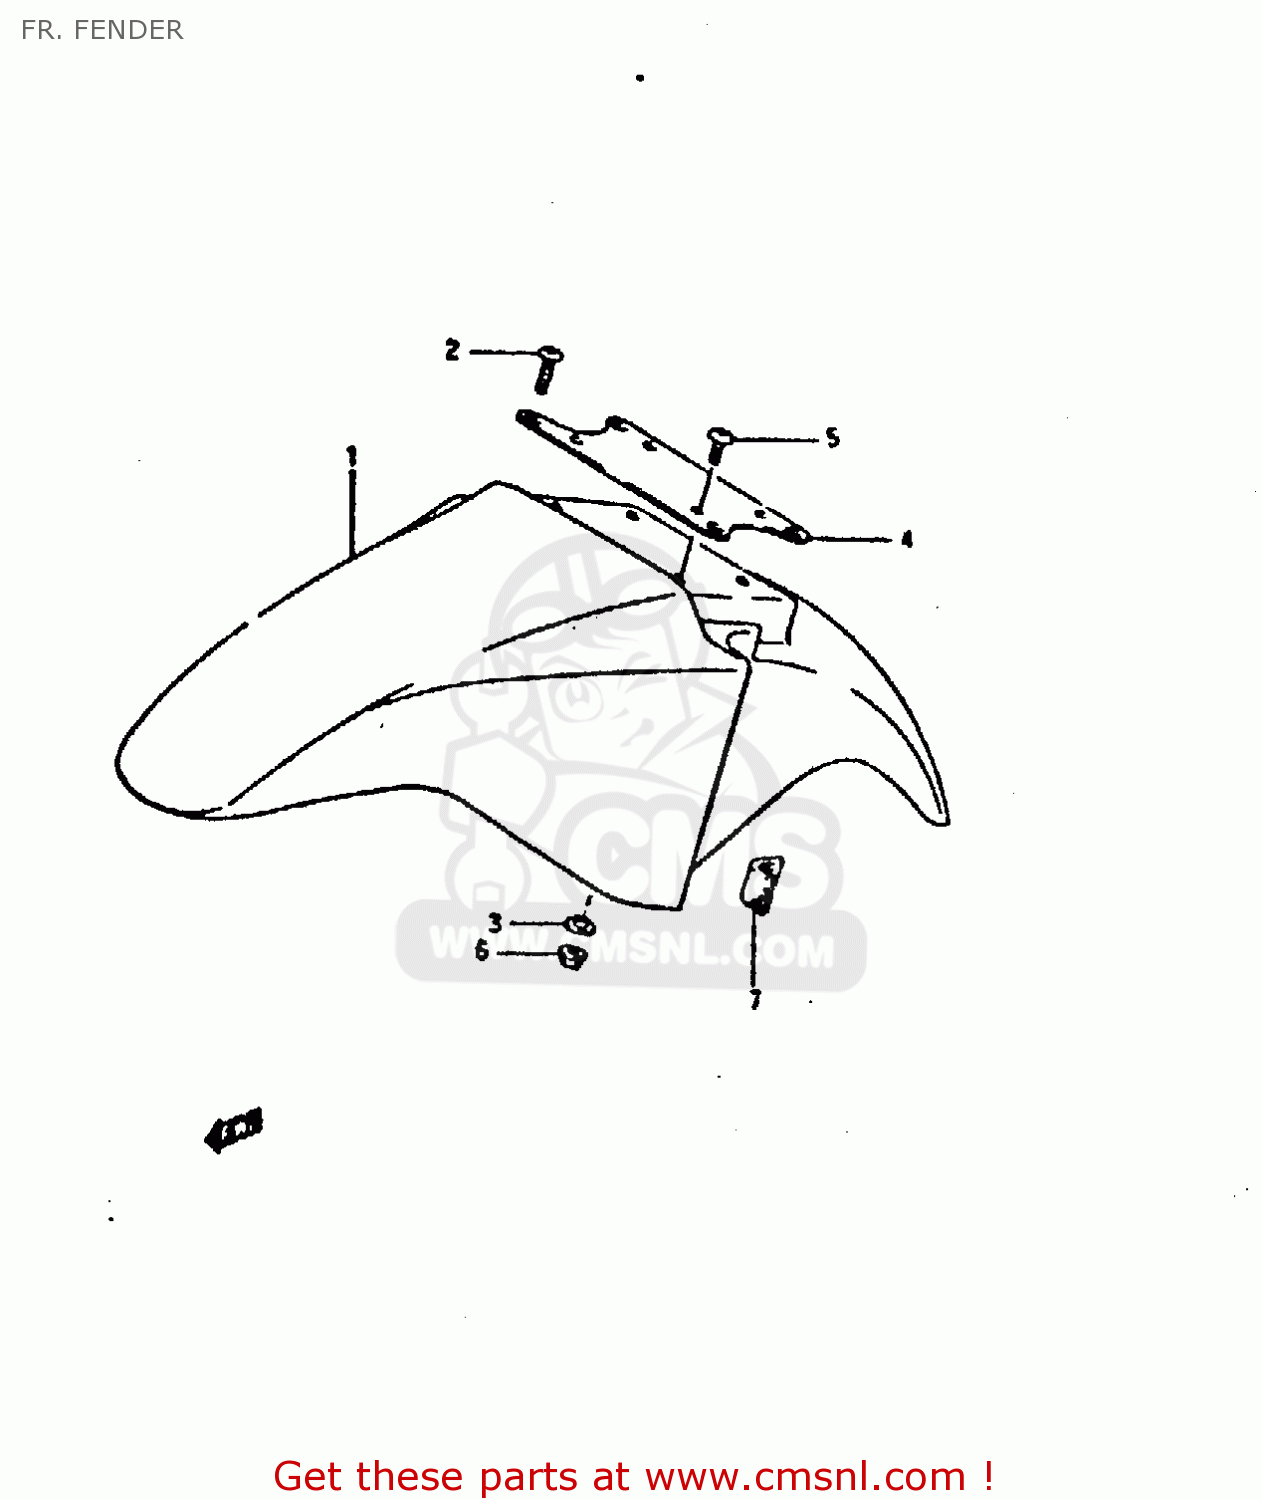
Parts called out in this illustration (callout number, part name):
1	FRONT FENDER
2	SCREW(6X12)
3	WASHER
4	BRACE,FR FENDER
5	SCREW
6	NUT
7	CUSHION,FRONT FENDER
